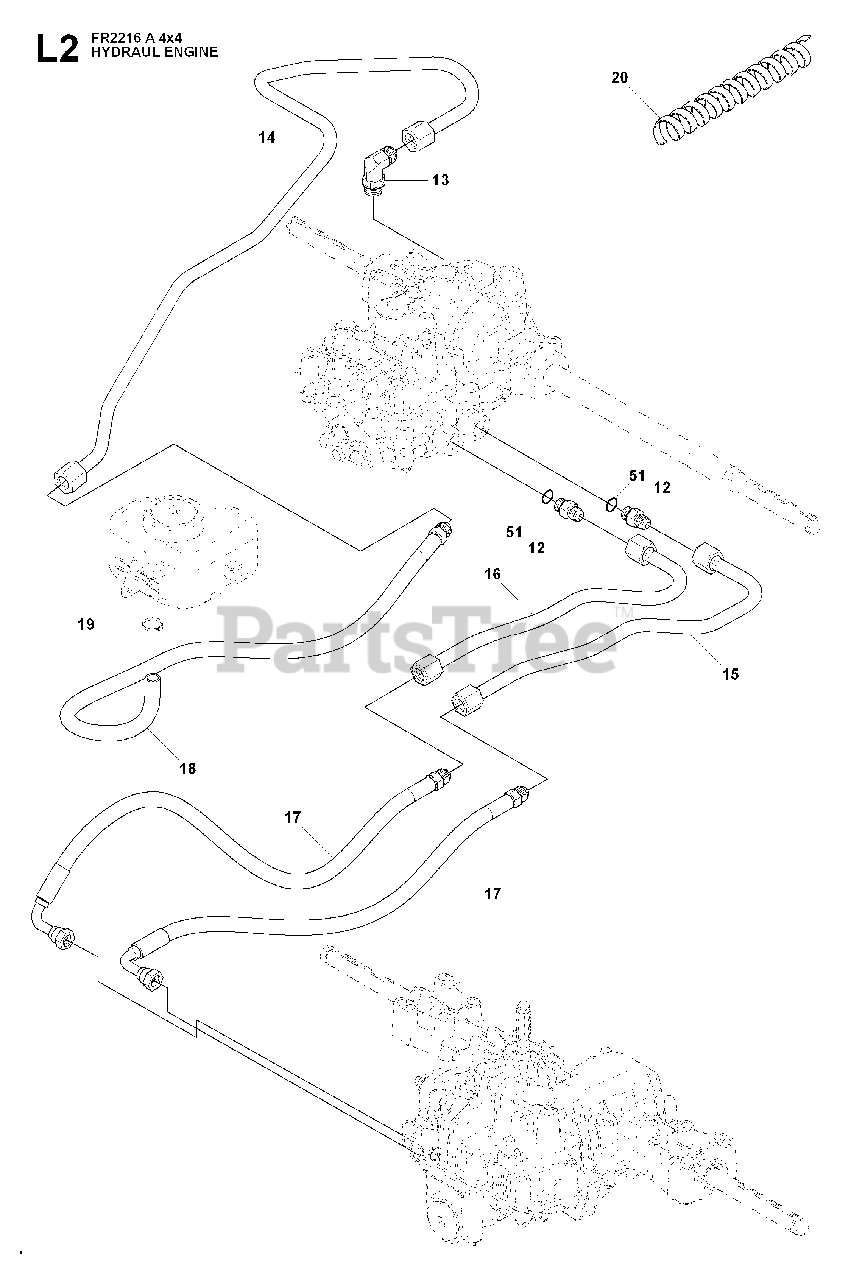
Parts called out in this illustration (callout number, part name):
12	PIPE FITTING
14	HYDRAULIC PIPE
15	HYDRAULIC PIPE
16	HYDRAULIC PIPE
17	HYDRAULIC HOSE
19	HOSE CLIP
20	PROTECTOR
